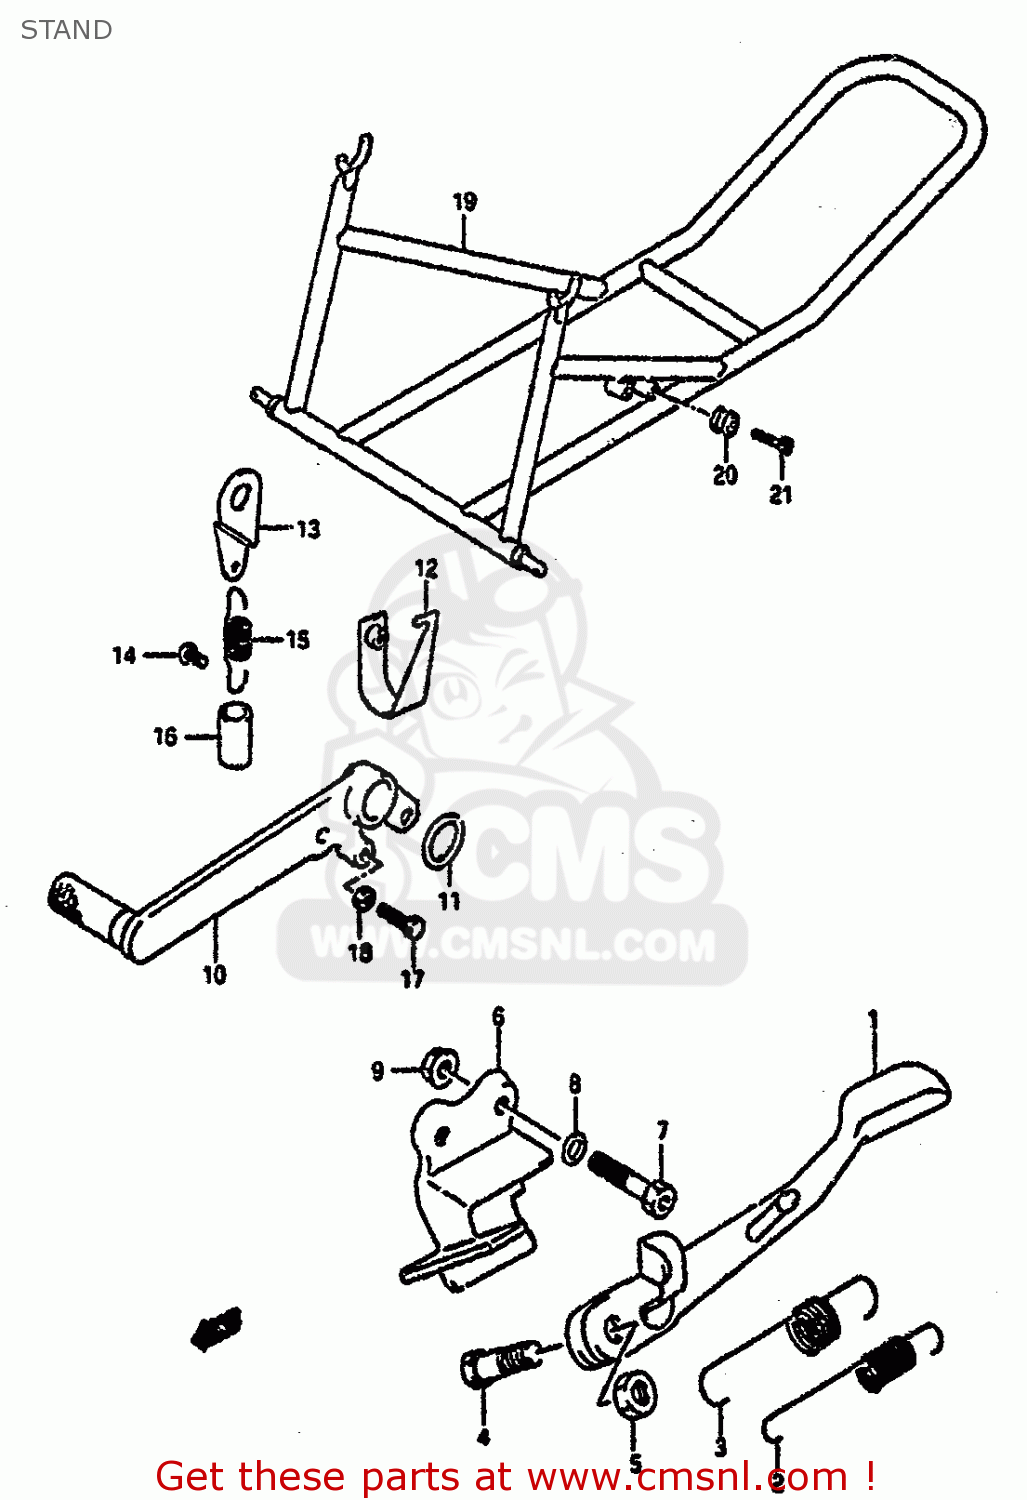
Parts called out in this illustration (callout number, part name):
1	STAND,PROP
2	SPRING
3	SPRING
4	BOLT(10X38)
5	NUT
6	BRACKET,PROP STAND
7	BOLT, FRONT RH
8	WASHER
9	NUT
10	PEDAL,BRAKE
11	WASHER(18X24X1)
12	PLATE,BRAKE SPRING,FRONT
13	BRACKET,STOP SWITCH SPRING
14	SCREW(6X12)
15	SPRING
16	TUBE,BRAKE SPRING GUIDE
17	BOLT
18	NUT 5MM
19	STAND ASSEMBLY,REAR
20	HOLDER,STAND
21	BOLT, REAR (8X30)
